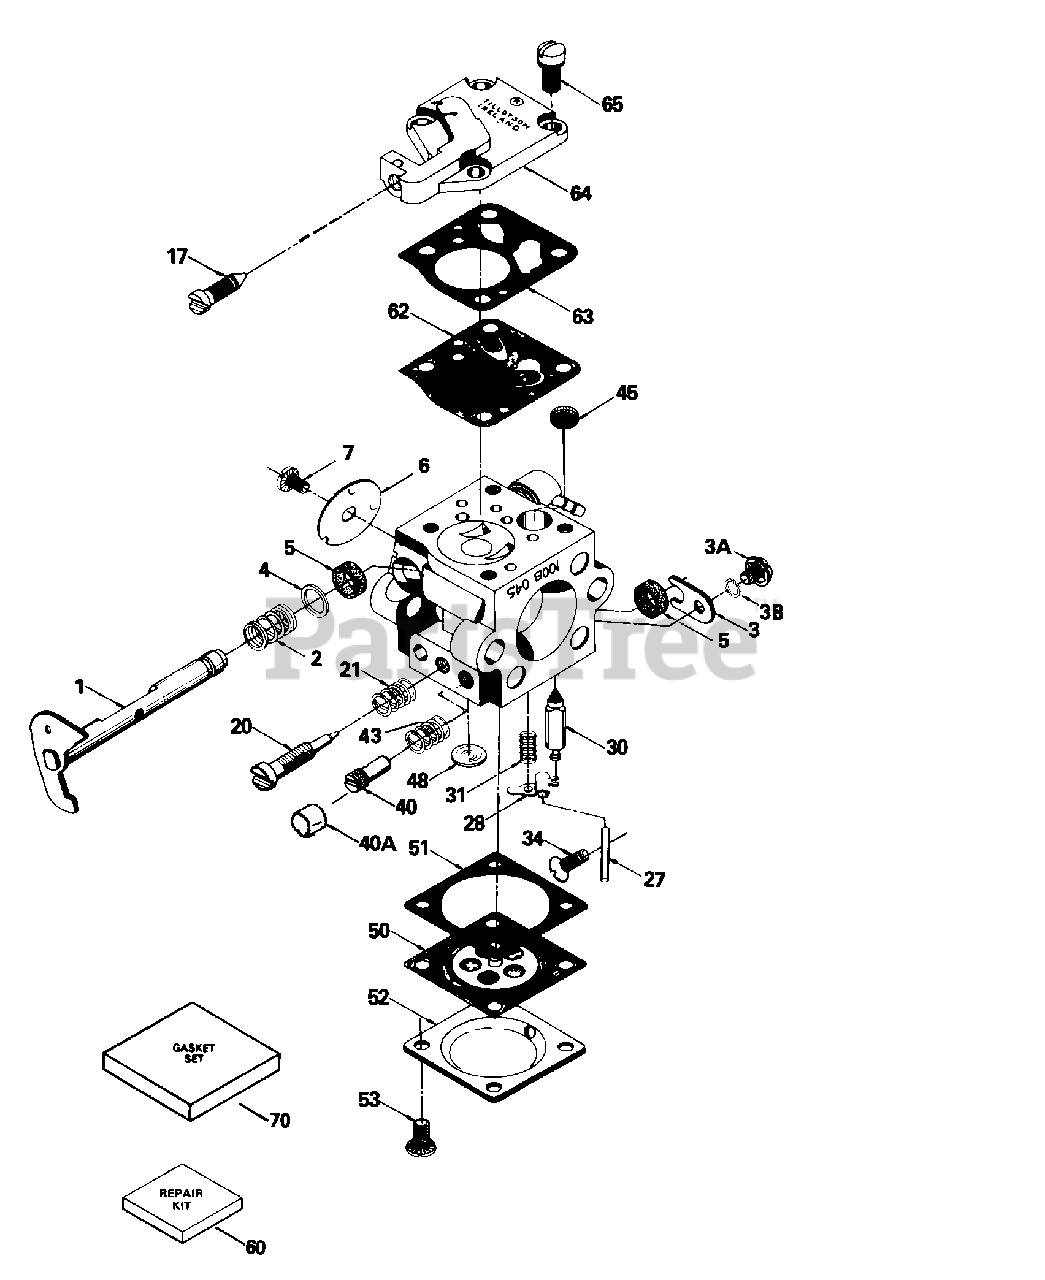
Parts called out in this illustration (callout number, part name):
1	Throttle Shaft & Lever Ass'y.
2	Throttle Return Spring
3	Dust Seal Retainer
3A	Dust Seal Retainer Screw
4	Dust Seal Washer
5	Dust Seal
6	Throttle Shutter
7	Throttle Shutter Screw
17	Idle Speed Screw
20	Idle Mixture Screw
21	Idle Tension Spring
27	Hinge Pin
28	* Metering Lever
30	* Inlet Needle
31	Metering Lever Spring
34	Metering Lever Pin Screw
40	High Speed Jet
40A	High Speed Jet Sealer Cap
45	* Fuel Inlet Screen
48	* Welch Plug
50	* Diaphragm (Included in 60 & 70)
51	* Cover Gasket (Included in 60 & 70)
53	Cover Screw
60	Repair Kit (Incl. items marked PK in notes) Incl. (1) each of part #'s6329 02, 632903, 632904, 632907,632908, 63 2915, 632918, 632919
62	* Pump Diaphragm (Included in 60 & 70)
63	* Pump Gasket (Included in 60 & 70)
64	Pump Cover
65	Pump Cover Screw
70	Diaghragm/Gasket Set (Incl. 50, 51, 6 2 & 63)
